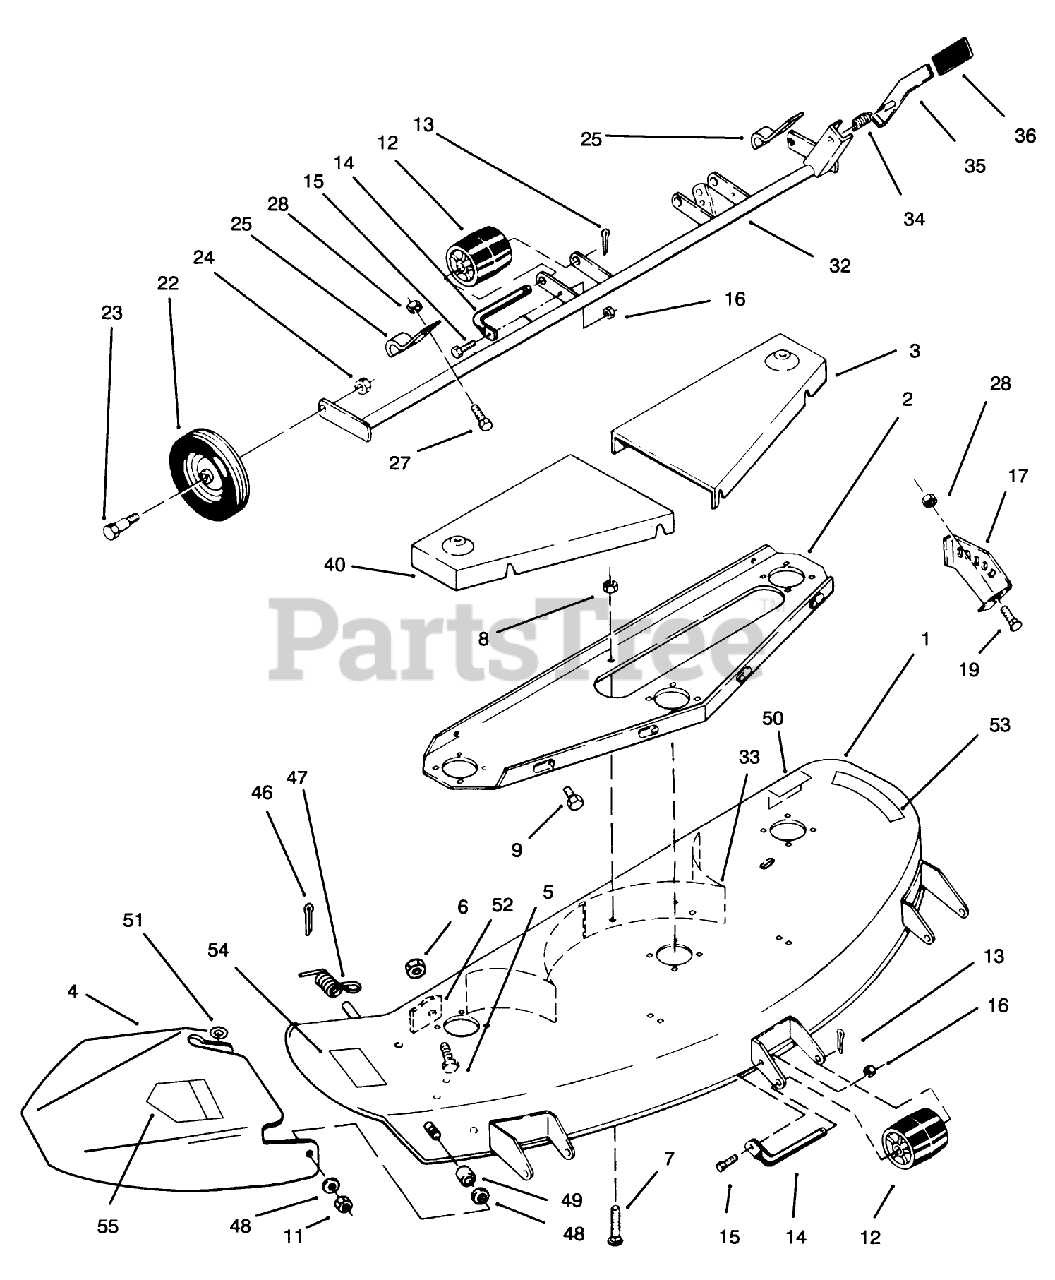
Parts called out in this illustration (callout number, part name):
5	SCREW-HH
6	NUT-LOCK, NI
7	BOLT-CARR
8	NUT-LOCK, NI
13	PIN-COTTER
14	ROLLER-SHAFT
15	SCREW-HH
16	NUT-LOCK, NI
19	BOLT-CARR
22	WHEEL
23	BOLT-SHOULDER
27	BOLT-CARR
28	NUT-LOCK, NI
33	BAFFLE-DECK RH
34	SPRING-COMPRESSION
46	PIN-COTTER
49	BUSHING-PIVOT
50	DECAL-HEIGHT & BELT
51	WASHER-FLAT
53	DECAL - DANGER
54	DECAL-DANGER, THROWN OBJECT
